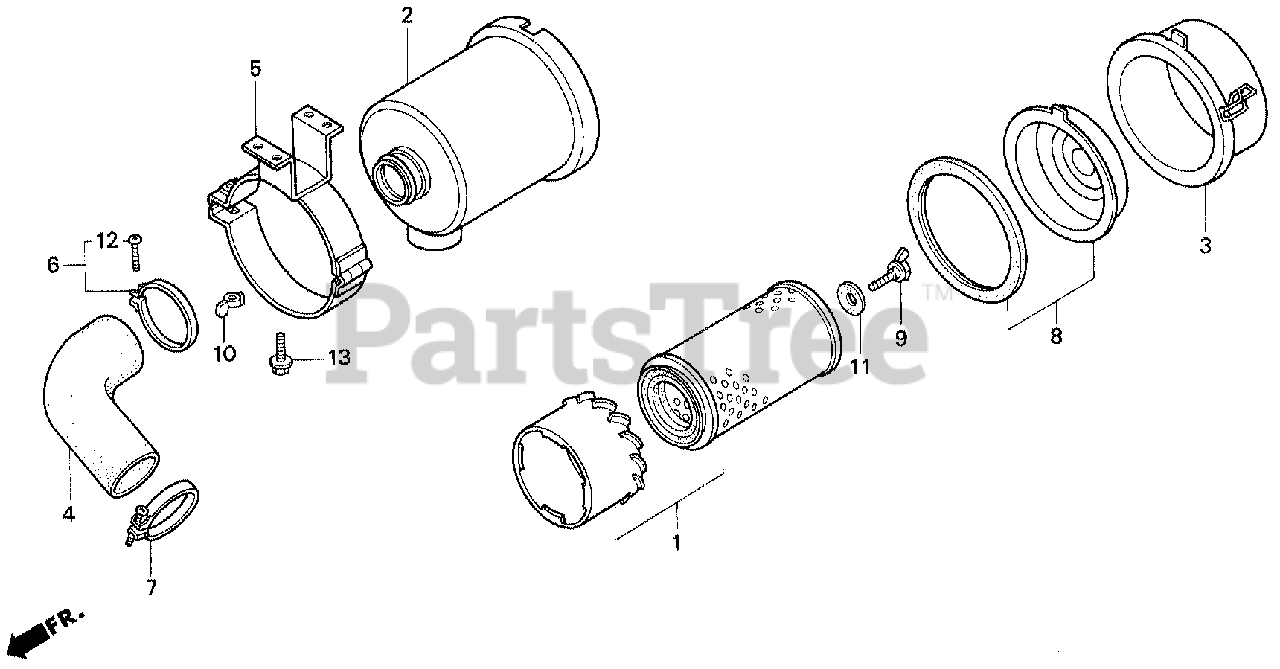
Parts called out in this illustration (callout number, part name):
1	ELEMENT, AIR CLEANER (DRY) Use from Frame SN 1003500.
1	ELEMENT, AIR CLEANER
1	ELEMENT, AIR CLEANER (DRY) Use up to Frame SN 1003499.
2	HOUSING, AIR CLEANER
3	COVER, AIR CLEANER
4	TUBE, AIR CLEANER CONNECTING
5	BAND, AIR CLEANER
6	BAND, CONNECTING TUBE
7	BAND, AIR CLEANER CONNECTING
7	BAND, AIR CLEANER CONNECTING TUBE (56)
8	PAN ASSY., DUST
9	BOLT, AIR CLEANER
10	WINGNUT, TOOL BOX SETTING
11	WASHER, AIR CLEANER
12	SCREW, PAN (4X20)
13	BOLT, FLANGE (8X16)
